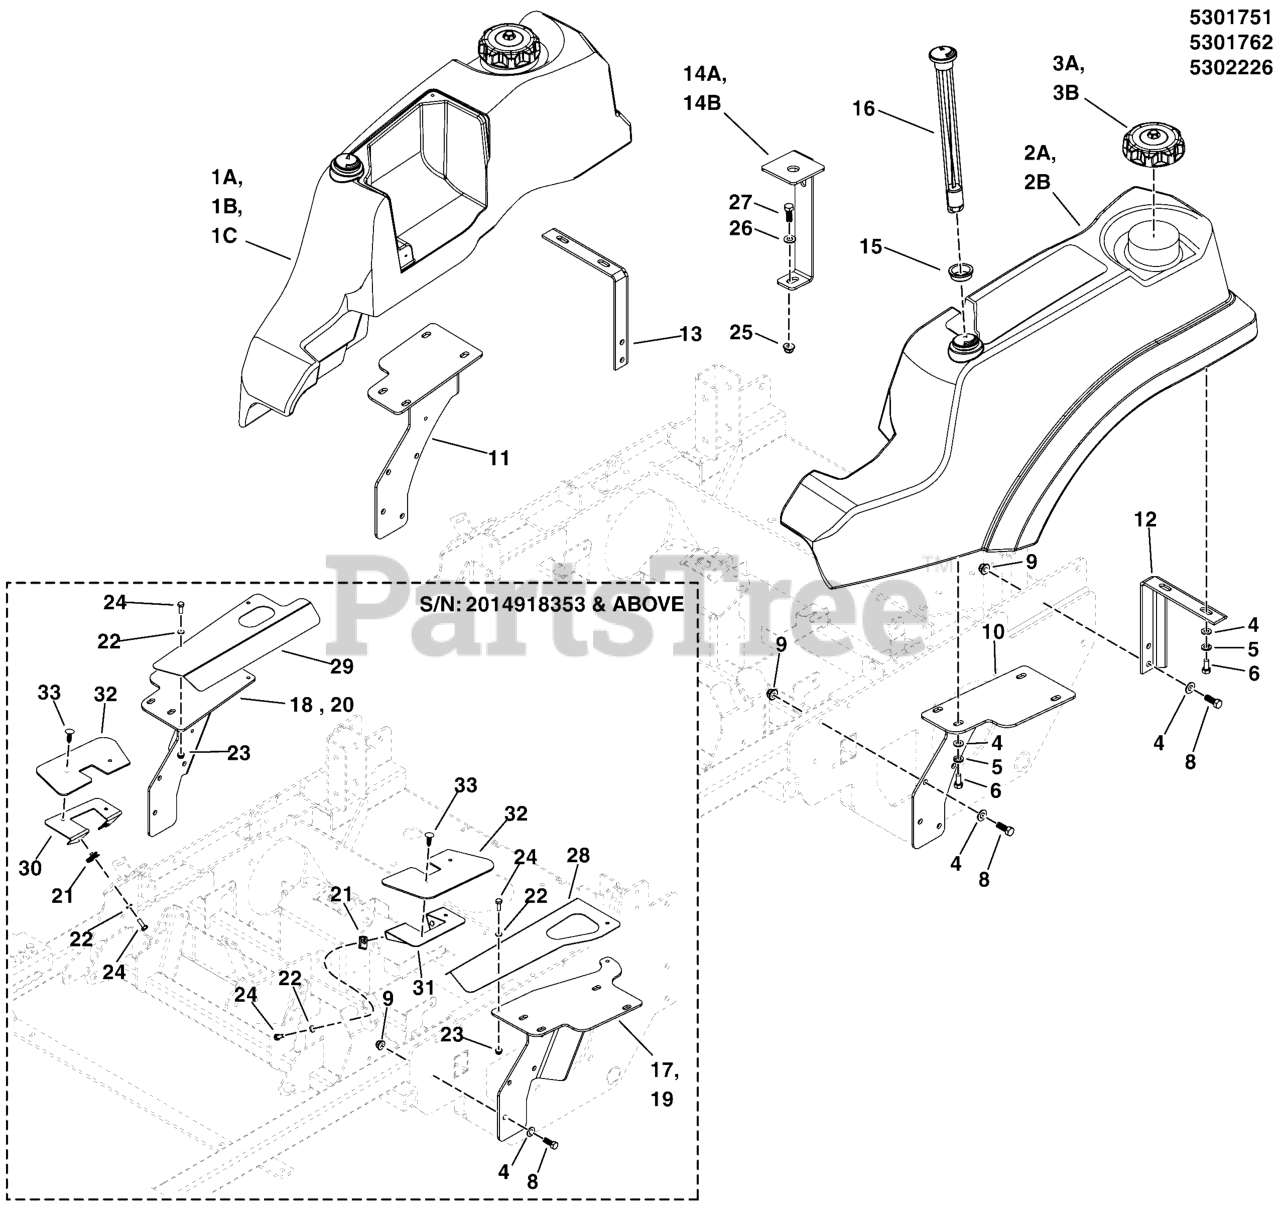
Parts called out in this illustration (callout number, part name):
1A	TANK, FUEL, 5 GAL, SNP-PRO, RH, 2013
1B	TANK, FUEL, SNAPPER PRO - RH
1C	TANK, FENDER, SNP-PRO, RH, 2013
2A	TANK, FUEL, 5.75 GAL, SNP-PRO, LH, 2013
2B	TANK, FUEL, SNAPPER PRO - LH
3A	FUEL CAP, 3-1/2", MANAGED VENT OUT, 12"
3B	CAP, GASOLINE, VENTED
4	WASHER, 5/16" SAE
5	WASHER, 5/16 LOCK CZ
6	BOLT, 5/16-18 X 3/4 GD5
8	BOLT, 5/16-18 X 1" GRD5 YZ
9	NUT, 5/16-18 HEX NYLOCK FLANGE NUT
10	WELD, FUEL TANK MOUNT - LH, S200XT - BLK
11	WELD, FUEL TANK MOUNT - RH, S200XT - BLK
12	MOUNT, REAR TANK, LH - BLK
13	WELD, TANK MOUNT, REAR, RH - BLK
14A	BRACKET, FUEL VALVE
14B	BRACKET, FUEL VALVE
15	GROMMET, FUEL GAUGE (SV)
16	GAUGE, FUEL, 12
17	WELD, FUEL TANK MOUNT - LH, S200XT - BLK
18	WELD, FUEL TANK MOUNT - RH, S200XT - BLK
19	WELD, FUEL TANK MOUNT - LH, 200XT - BLK
20	WELD, FUEL TANK MOUNT - RH, 200XT - BLK
21	BODY CLIP, 1/4-20 X 1/2" DEEP
22	WASHER, 1/4 SAE
23	NUT, 1/4-20 Hex Nylock Flange
24	BOLT, 1/4"-20 X 3/4" GD5 YZ
25	NUT, 3/8 - 16 HEX NYLOCK FLANGE
26	WASHER, 3/8 SAE
27	BOLT, 3/8-16 X 1" GD5 CZ
28	GUARD, SEAT, LH - BLK
29	GUARD, SEAT, RH, F210Z - BLK
29	GUARD, SEAT, RH - BLK
30	PLATE, FLAP MOUNTING, S200XT - RH - BLK
31	PLATE, FLAP MOUNTING, S200XT - LH - BLK
32	FLAP, CONTROL, S200XT
33	PUSH RIVET (TREE TYPE), BLACK
